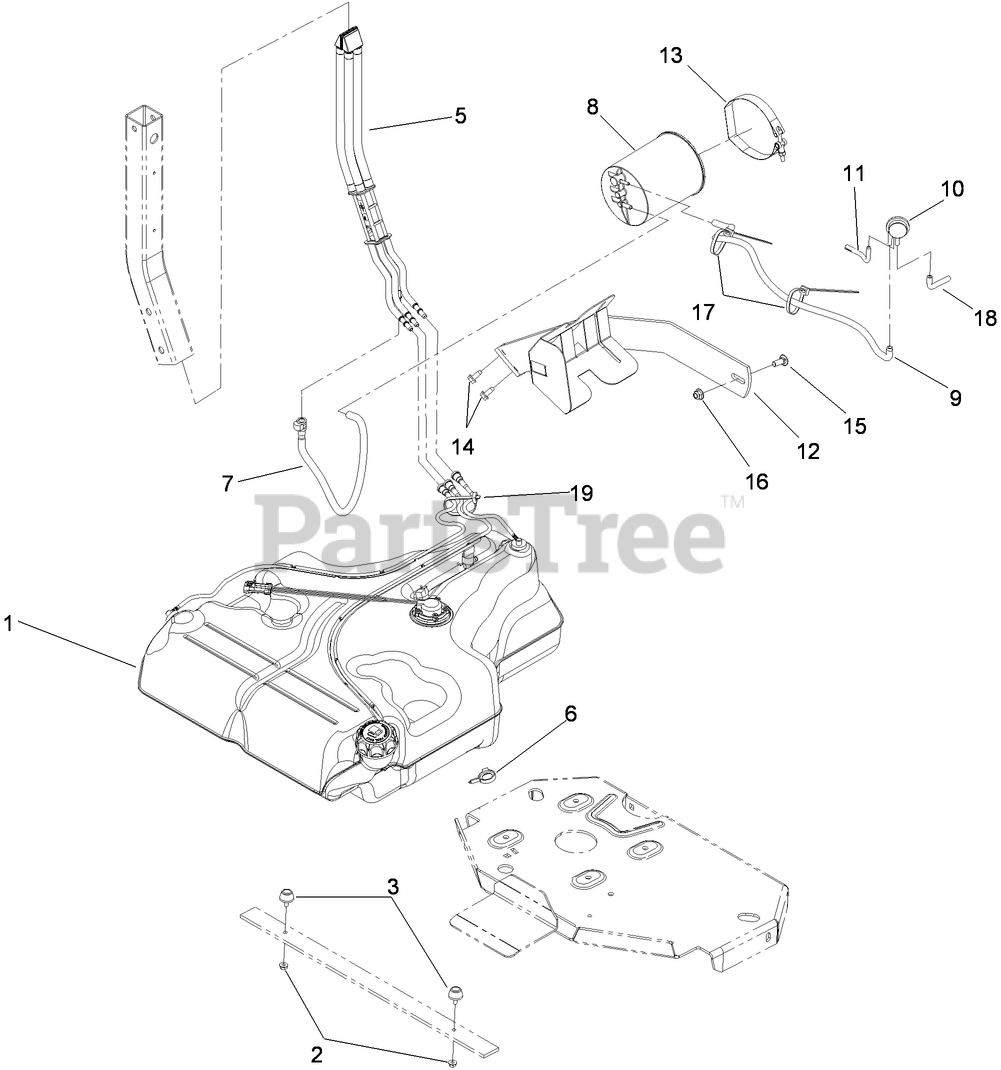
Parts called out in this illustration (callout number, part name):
1	FUEL TANK ASM
2	NUT-HF
3	BUMPER-RUBBER
5	FUEL MANIFOLD VENT ASM
6	CLAMP-HOSE
7	VENT HOSE ASM
8	CANISTER-CARBON, 1200CC
9	HOSE-VENT, FORMED
10	VALVE-CONTROL, VACUUM
11	HOSE-VENT, FORMED
12	MOUNT-CANISTER
13	CLAMP-T-BOLT
14	SCREW-HWHTF
15	SCREW-CARR
16	NUT-HF, NI
17	TIE-PLASTIC
18	HOSE-VENT, FORMED
19	TIE-PLASTIC
